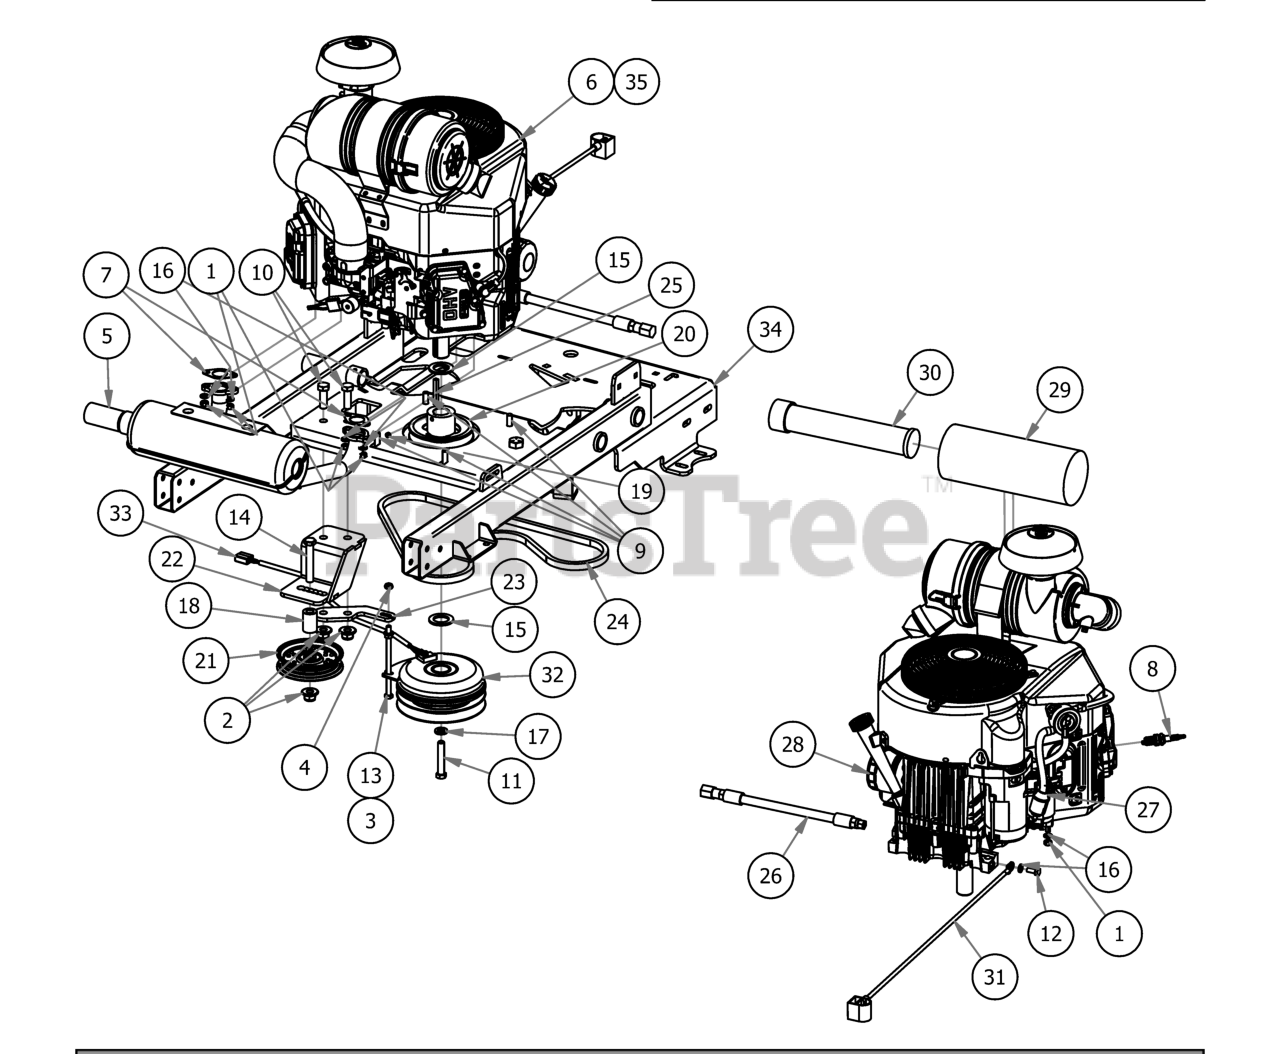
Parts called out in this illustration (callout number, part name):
1	M8-1.25 Zinc Nut
2	1/2-13 NYLON INSERT FLANGE LOCKNUT ZINC
3	5/16" Flange Nut
4	5/16-18 Nylock Jam Nut 1/2 Nut
5	Exhaust-Stand On-FX691V Kawasaki
7	Exhaust Gasket
8	Spark Plug - Kawasaki
9	3/8 x 1 1/8 bolt
10	1/2" x 1 1/2" Hex Bolt
11	7/16" x 2 1/2" Hex Bolt
12	M8x1.20x20MM Hex head bolt
13	5/16-18 x 5-1/2 GR 5 Hex Bolt
14	1/2-13 x GR 5 Hex Bolt Zinc
15	1 1/8" Flat Spacer
16	5/16 SPLIT LOCKWASHER ZINC
17	7/16" Lock Washer
18	.502 ID X .750 OD X 1.500 Long Spacer
19	5/16 Set Screw
20	4 3/4 Motor Pulley
21	4 3/4 Idler Pulley - ABFI-76
22	Idler Pulley Bracket Weldment
23	2019 Stand On Clutch Stop Bracket
24	2019 Stand On Pump Belt (Timken# 47-2827)
25	1/4 x 2 Square key Stock
26	Kawasaki Oil Drain
27	Universal Inline Fuel Filter
28	Oil Filter
29	Canister Air Filter- Outer
30	Canister Air Filter- Inner
31	24" Black Ground Cable
32	Clutch Assembly
33	Clutch Pigtail
34	2019 Stand On Frame Weldment
35	Kawasaki Harness Adapter
